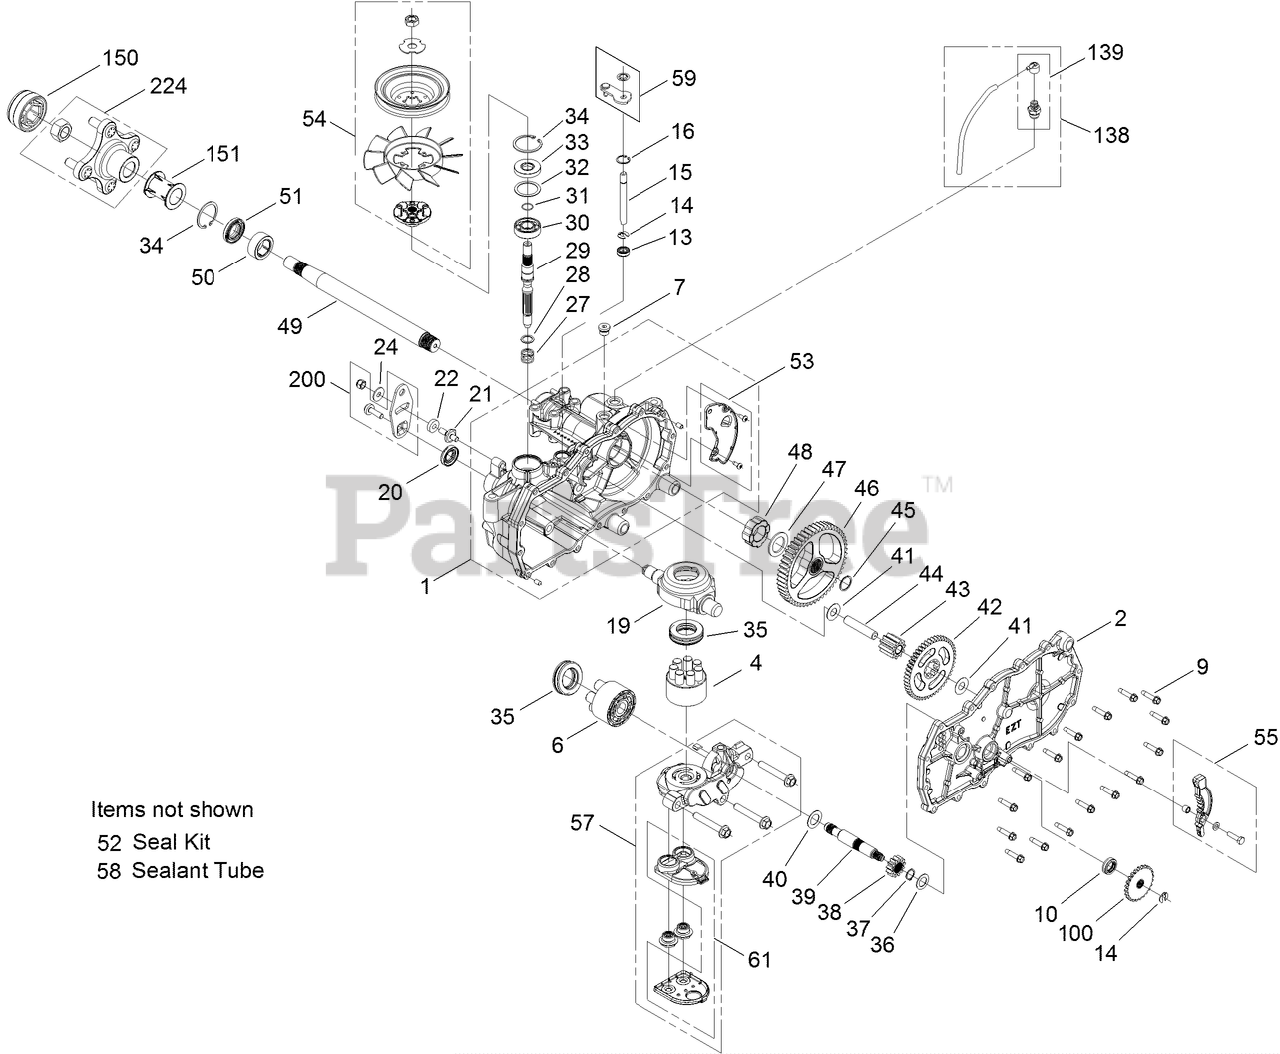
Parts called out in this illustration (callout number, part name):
1	MAIN HOUSING ASM
2	SIDE ASM
4	PUMP BLOCK ASM
6	CYLINDER BLOCK KIT
7	PLUG-THREAD, STRAIGHT
9	SCREW-HHF
10	SEAL-OIL
13	SEAL-LIP
14	RING-RETAINING, EXTERNAL
15	ROD-BYPASS
16	RING-RETAINING, INTERNAL
19	SWASHPLATE-TRUNNION
20	SEAL-LIP
22	PUCK-FRICTION
24	WASHER
28	WASHER
29	SHAFT-INPUT
30	BEARING-BALL
31	RING-RETAINING
32	SPACER
33	SEAL-LIP
34	RING-RETAINING
35	BEARING-THRUST
36	WASHER-FLAT
37	RING-RETAINING
38	GEAR-PINNION, 13T
39	SHAFT-MOTOR
40	WASHER
41	WASHER
42	GEAR-10T/48T
43	GEAR-JACKSHAFT, 10T
44	PIN-JACKSHAFT
45	RING-SPIRAL, RETAINING
46	GEAR-52T, BULL
47	WASHER
48	BEARING-SLEEVE
49	SHAFT-AXLE
50	BUSHING-AXLE
51	SEAL-LIP
53	EXPANSION PLATE KIT
55	BRAKE ARM KIT
57	CENTER SECTION FILTER KIT
59	BYPASS KIT
61	FILTER KIT
100	DISC-BRAKE, COG
138	BREATHER KIT
139	BREATHER ASM
150	COVER-NUT, AXLE
151	TUBE-AXLE
200	CONTROL ARM KIT
